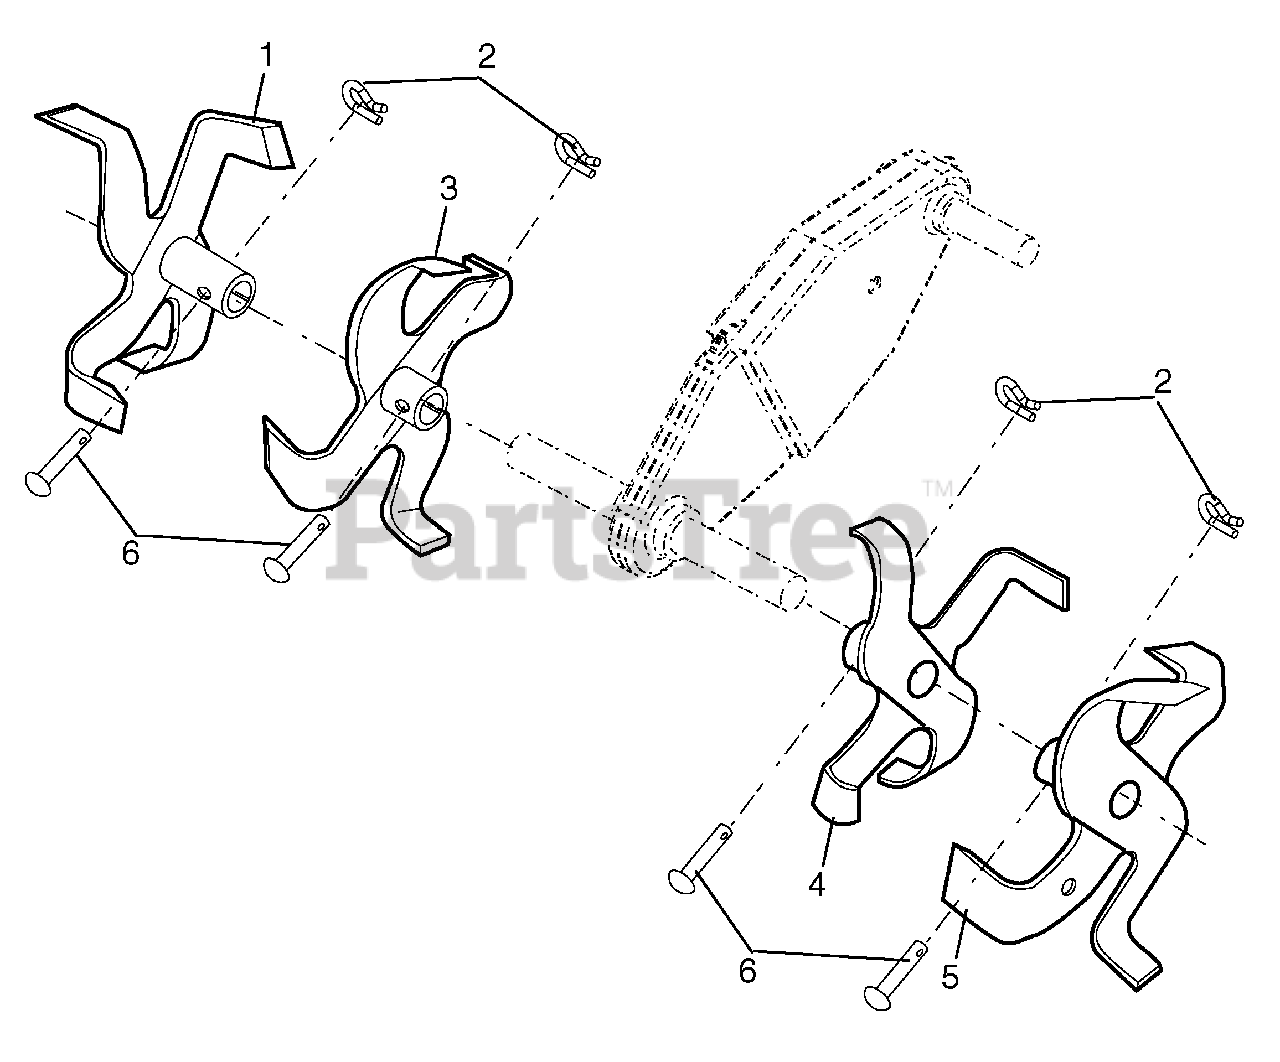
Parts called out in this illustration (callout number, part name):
1	Tine, Outer, R.H.
2	Retainer, Spring
3	Tine, Inner, R.H.
4	Tine, Inner, L.H.
5	Tine, Outer, L.H.
6	Pin, Clevis
